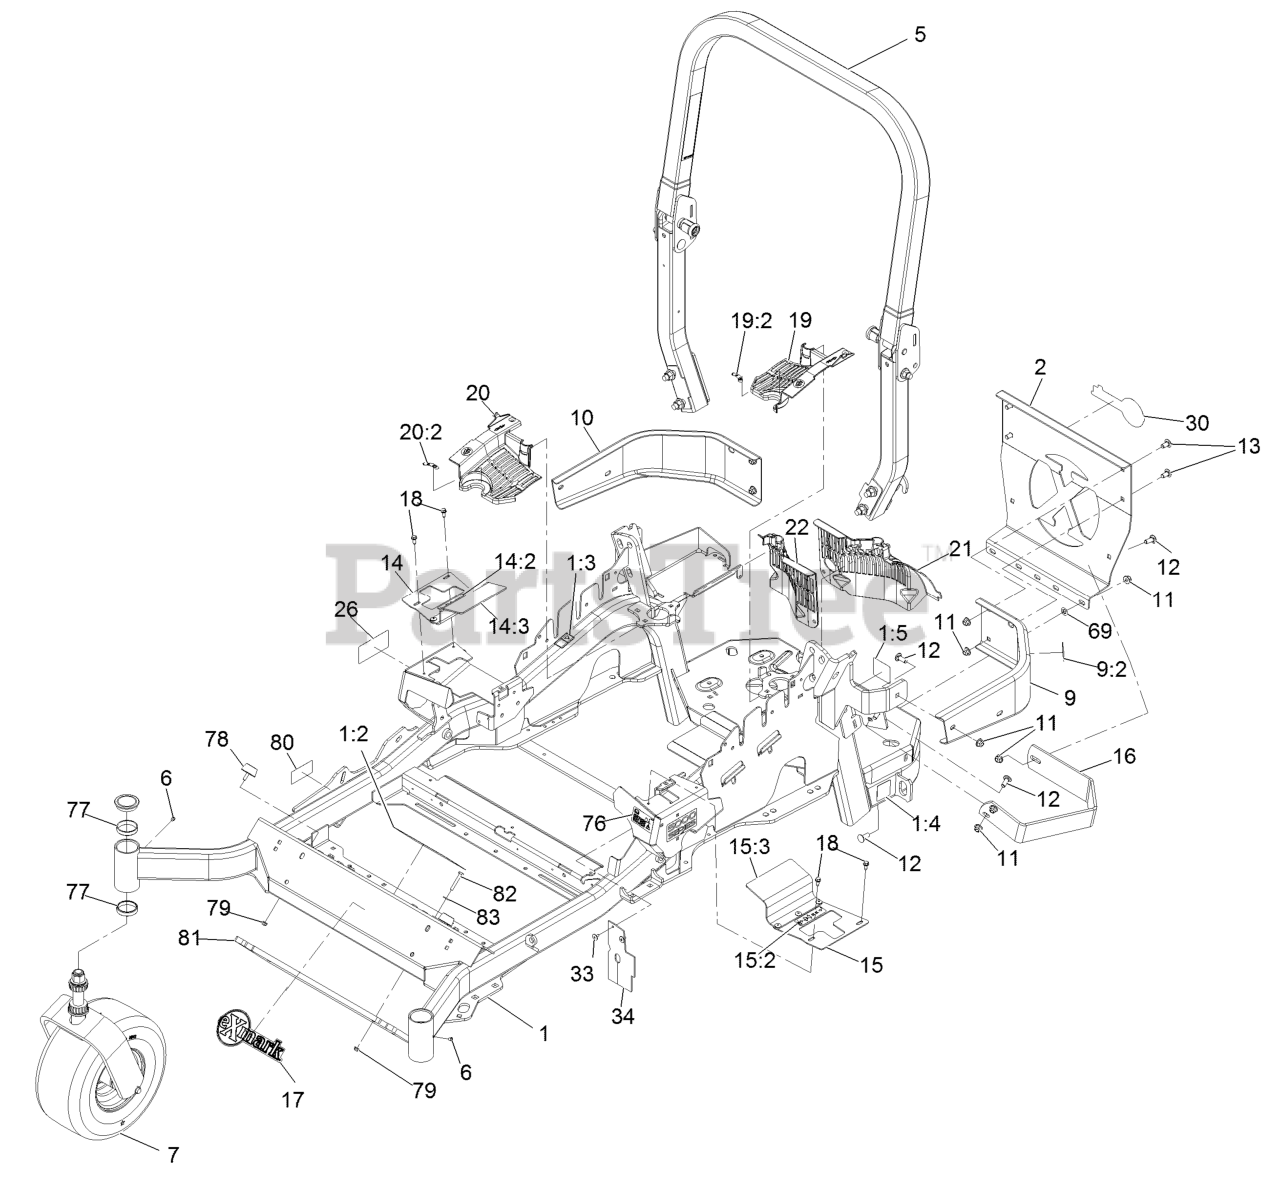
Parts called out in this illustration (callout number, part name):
1	MAINFRAME ASM
1:2	DECAL-DANGER
1:3	DECAL-WARNING
1:4	DECAL-HAZARD, PINCHED FINGER
1:5	DECAL-SPARK ARRESTER
2	PLATE,REAR GUARD
5	ASM,ROPS SERVICE EXMARK
7	Caster Wheel ASM
9	LH BUMPER ASM
9:2	DECAL-WARNING
10	BUMPER-RH
11	NUT-HF, NI
12	SCREW-CARR
13	SCREW-CARR
14	RH MOTION CONTROL COVER A
14:2	DECAL-CONTROL, MOTION
14:3	FLAP-RUBBER
15	LH MOTION CONTROL COVER A
15:2	DECAL-CONTROL, MOTION
15:3	FLAP-RUBBER
16	GUARD-MUFFLER
17	DECAL-EXMARK LOGO
18	SCREW-HWH
19	LH HYDRO GUARD ASM
19:2	DECAL-OIL, HYDRO
20	RH HYDRO GUARD ASM
20:2	DECAL-OIL, HYDRO
21	GUARD-HYDRO, REAR (LH)
22	GUARD-HYDRO, REAR (RH)
26	DECAL-X-SERIES
30	DECAL-EXMARK LOGO
33	RIVET-POP
34	DEFLECTOR-AIR FLOW
69	NUT-PUSH
76	DECAL-FUEL FILL, CE
77	CUP-BEARING
80	Decal-Patent
81	WEIGHT-TOE BOARD
82	SCREW-HH
83	WASHER-FLAT
